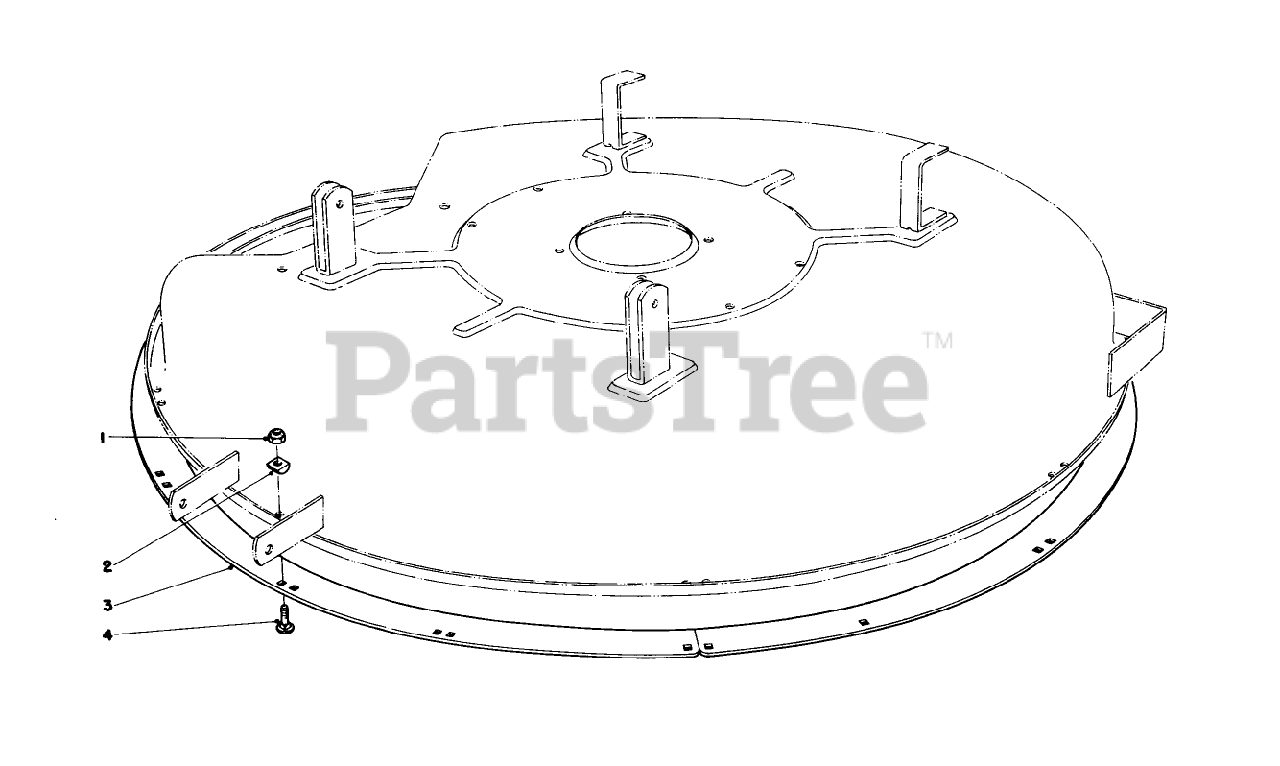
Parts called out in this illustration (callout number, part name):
1	NUT-LOCK, NI
3	DECK RING *B
4	BOLT-CARR
